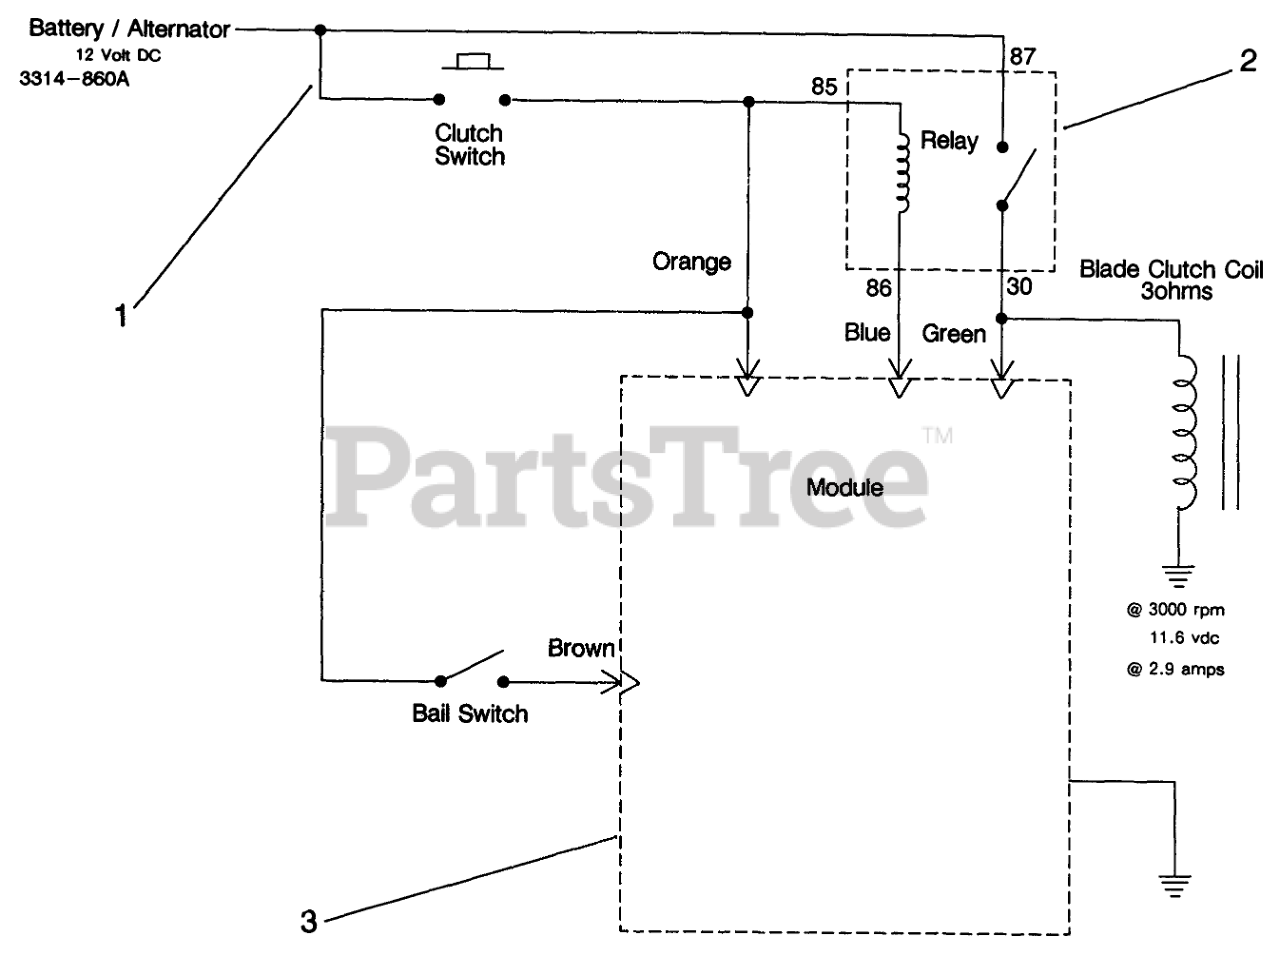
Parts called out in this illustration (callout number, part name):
1	Wire Harness
2	Module
3	RELAY
